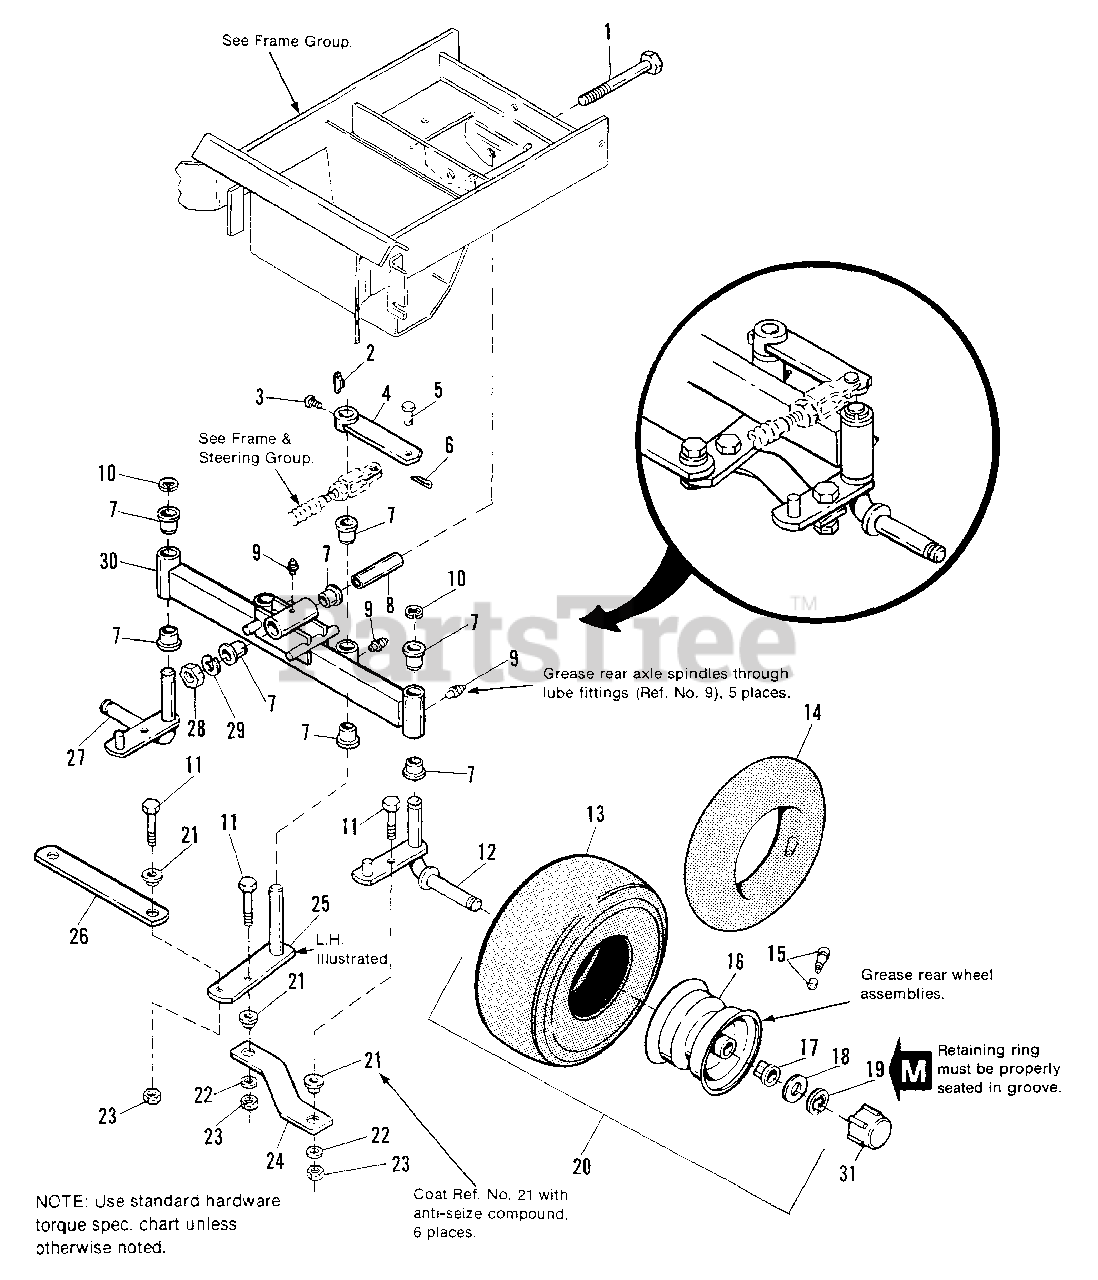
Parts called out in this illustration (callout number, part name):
1	CAPSCREW, 1/2-13 x 4
2	KEY, Hi-Pro, 3/16 x 5/8
3	SETSCREW, Sq. Hd., 1/4-20 x 3/8
4	STEERING ARM ASSY., Upper
5	PIN, Steering Arm
6	COTTER PIN, 1/2
7	BUSHING, Nylon
8	TUBE, Pivot Support
9	FITTING, Lube
10	E-RING, Retaining
11	CAPSCREW, Hex, 3/8-16 x 1-1/4
12	SPINDLE ASSY., L.H.
13	TIRE, Turf, 4.10/3.50-4 (Carlisle)
14	TUBE, 4.10/3.50-4 (Service Only)(See note below.)
15	VALVE STEM & CAP
16	WHEEL ASSY. (Incl. Ref. No. 17)
17	BEARING, Wheel
18	WASHER, Wheel
19	E-RING, Retaining, Wheel
20	WHEEL & TIRE ASSY., 4.10/3.50-4
22	WASHER, 3/8
23	LOCKNUT, 3/8-16
25	STEERING ARM ASSY., L.H. (Shown)
27	SPINDLE ASSY., R.H.
28	NUT, 1/2-13
29	LOCKWASHER, 1/2
30	REAR AXLE ASSY.
31	CAP, Threaded
